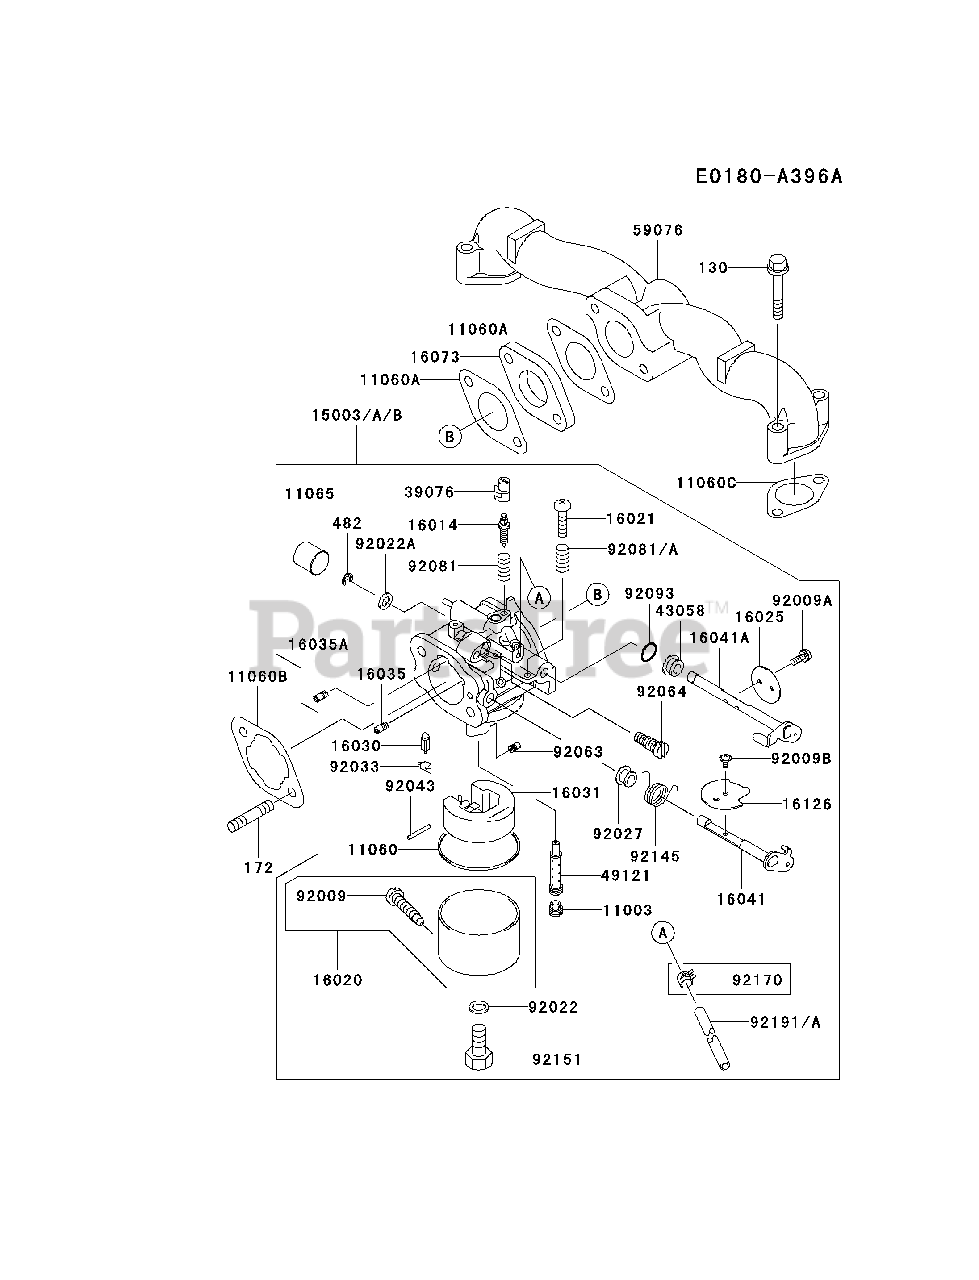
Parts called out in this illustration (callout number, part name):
130	BOLT-FLANGED
172	BOLT-STUD
482	CIRCLIP-TYPE-E
